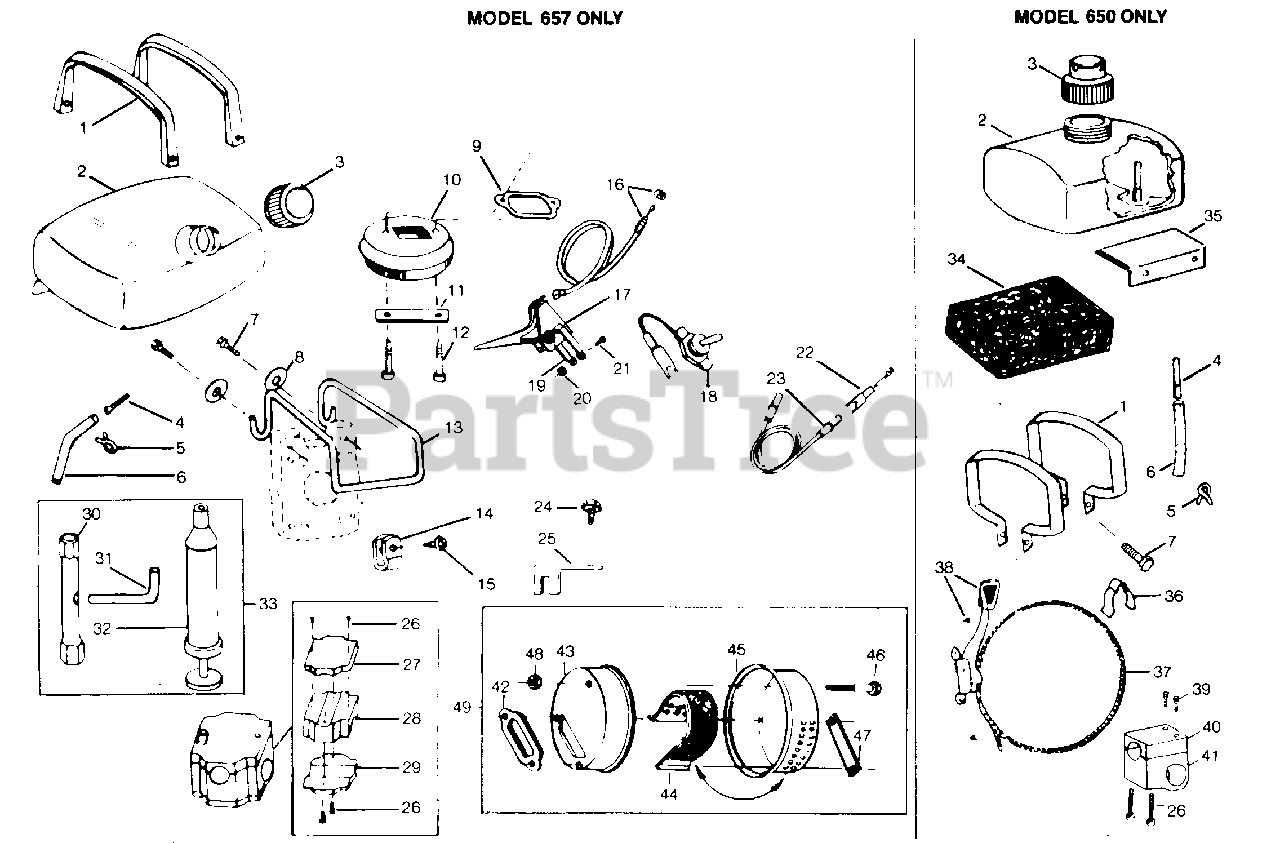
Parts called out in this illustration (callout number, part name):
1	Strap, - Fuel Tank
1	Model 657
1	Model 650
2	Tank,-Fuek-Plastic w/Filter
2	Model 657
2	Model 650
3	Cap,-Fuel Tank-Plastic
4	Filter, - Fuel Tank
5	Clip, - Fuel Hose
6	Model 657
6	Model 650
7	Screw #1/4-20x5/8"
8	Washer,-Flat Model 657
9	Gasket,-Exhaust Model 657
10	Muffler Model 657
11	Tab Lock Model 657
12	Screw, Hex Hd.-#1/4-20x2-5/16" Model 657
13	Cradle, Fuel Tank Model 657
14	Clip, Retaining Model 657
15	Screw, (Slot Hd) Clip Model 657
16	Throttle Control Cable w/nut Model 657
17	Throttle Control over Assembly Model 657
18	Previous Style Model 657
18	Current Style Model 657
19	Throttle Control Clamp Model 657
20	Nut (Hex #10-32)-Switch Bracket Model 657
21	Screw (Pan Hd.)-Switch Bracket Model 657
22	Wire Connector & Cover Model 657
23	Switch Harness Lead Model 657
24	Screw-Cable Clamp #1/4-20x3/8" Model 657
25	Throttle Control Bracket Model 657
26	Screw, Allen Hd #5/16-18x7/8" Model 657
27	Upper Cap Model 657
28	Middle Block Model 657
29	Lower Cap Model 657
30	Box Wrench Model 657
31	Allen Wrench Model 657
32	Grease Gun Model 657
33	Tool Kit (Incl. #30, 31 & 32) Model 657
34	Fuel Tank Baffle Model 650
35	Fuel Tank Bracket Model 650
36	Throttle Control Clip Model 650
37	Throttle Control Complete Model 650
38	Screw Model 650
39	Screw Model 650
40	Upper Clamp Model 650
41	Lower Clamp Model 650
43	Muffler, Inlet
44	Baffle w/Screen
45	Muffler, Outlet
47	Screw 1/4"-20x1-3/4"
48	Nut, Flex-Loc 1/4" 20
49	Kit-Spark Arresting Muffler (Optional)
